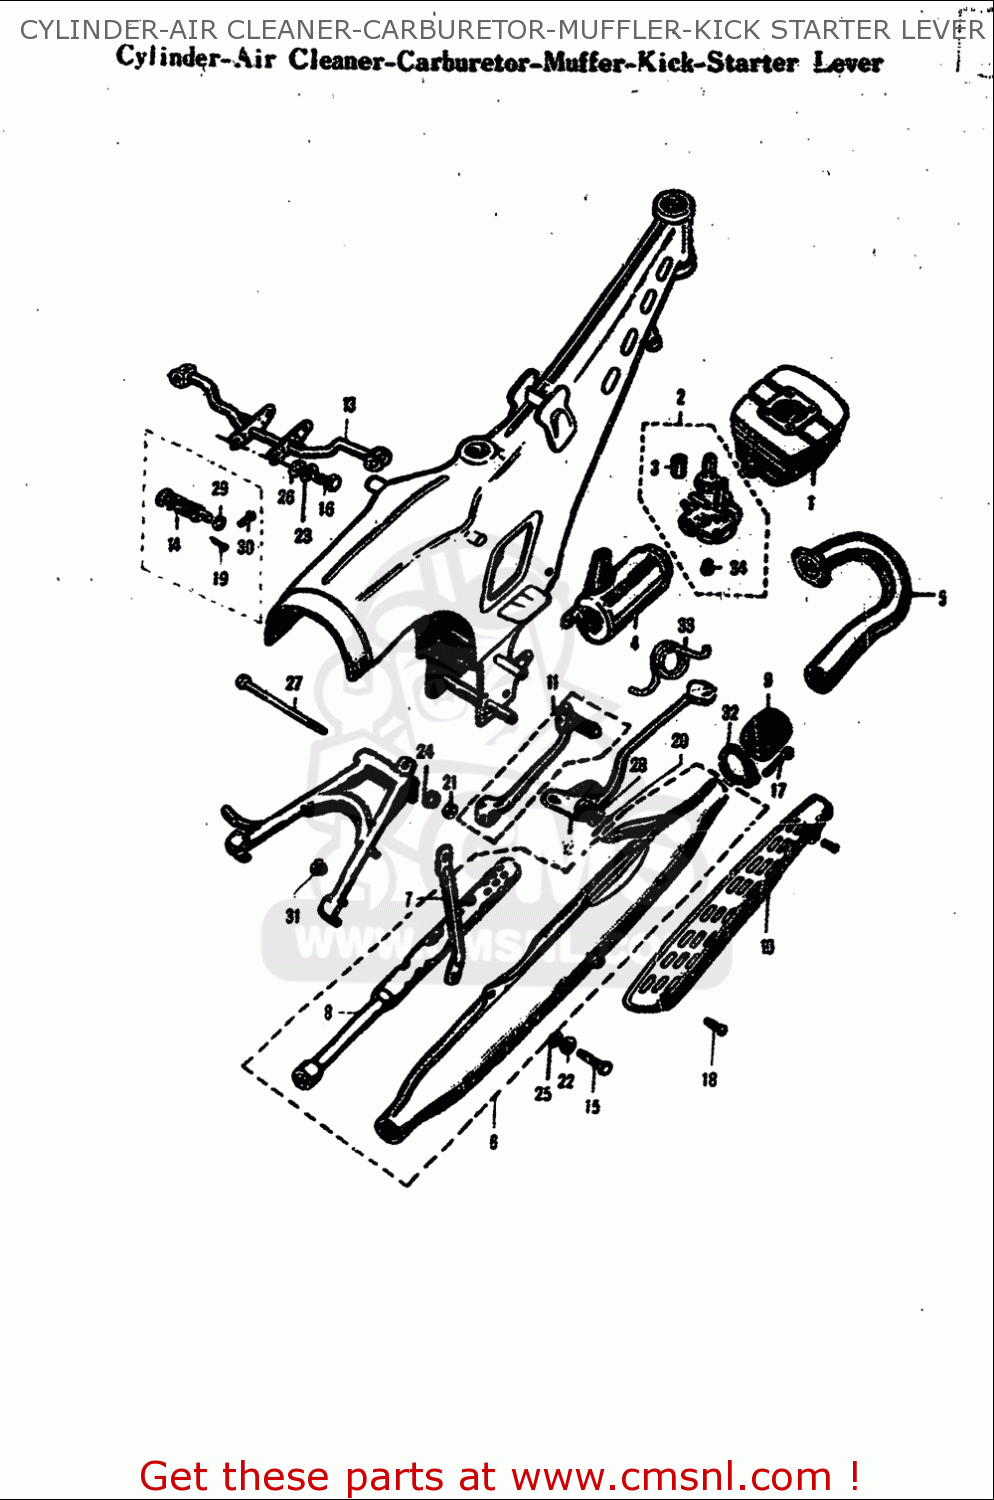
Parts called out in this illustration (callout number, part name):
16	BOLT
21	NUT
22	WASHER,LOCK
23	WASHER,LOCK
24	WASHER,LOCK
25	WASHER
26	WASHER
27	BOLT
28	WASHER(15.5X26X2.3)
29	WASHER(22.5X38X1)
30	PIN
31	CUSHION(11.5X22X20)
